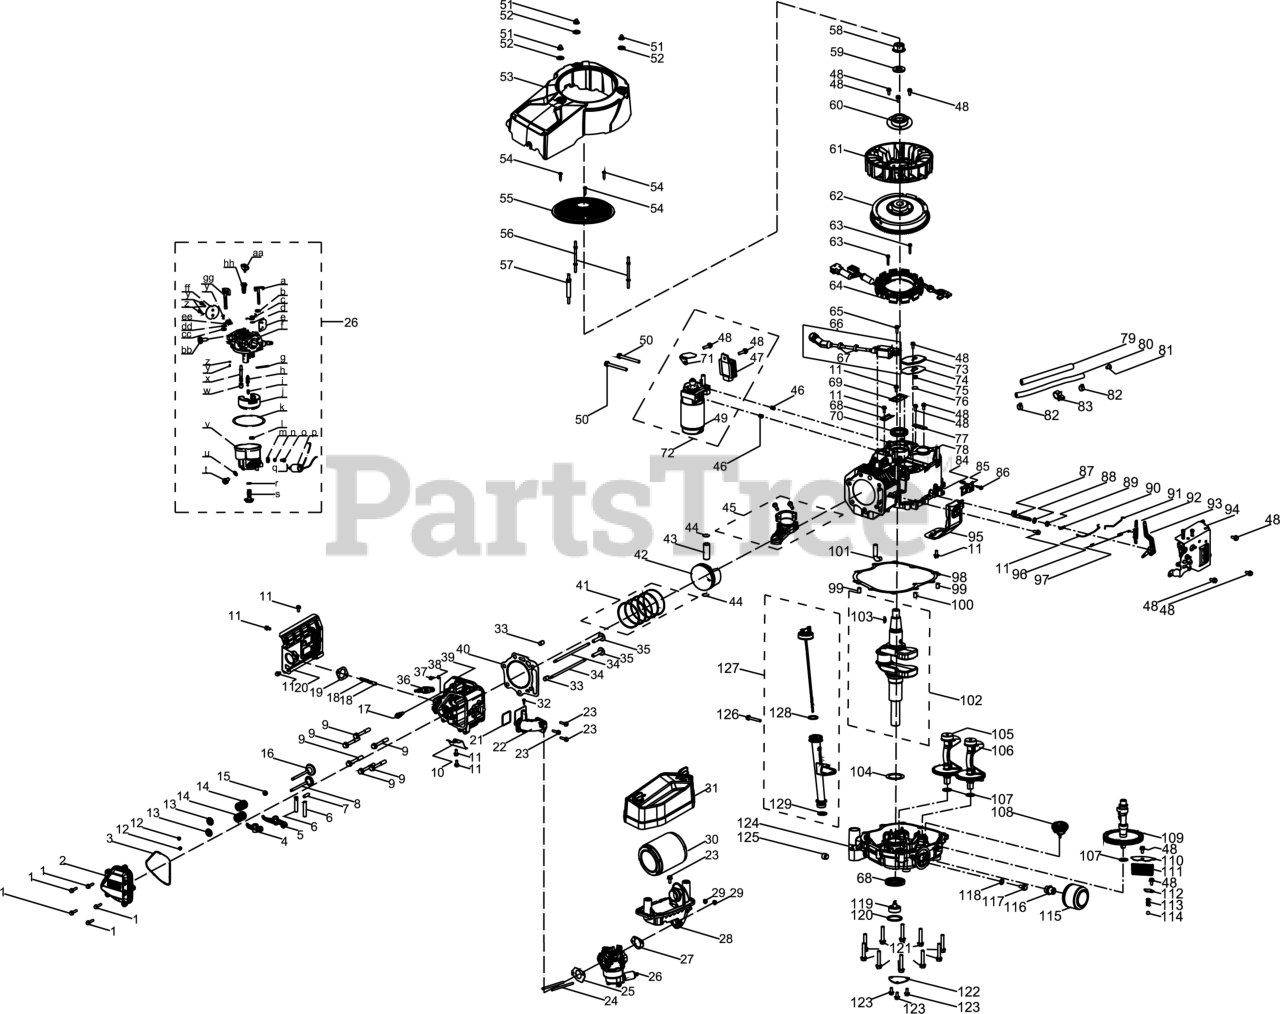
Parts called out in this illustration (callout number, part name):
1	BOLT M6-1 x 25 GR8.8
2	VALVE COVER
3	VALVE COVER GASKET
4	ROCKER ARM (INTAKE)
5	ROCKER ARM (EXHAUST)
6	ROCKER ARM SHAFT
7	CAMSHAFT PIN
8	EXHAUST VALVE
9	BOLT M10-1.25 x 70
10	HEAT SHEILD
11	BOLT M6-1 x 12 GR8.8
13	VALVE SPRING SEAT
14	VALVE SPRING
15	INTAKE VALVE SEAL
16	INTAKE VALVE
19	EXHAUST GASKET
20	BAFFLE BRACKET
21	INTAKE PIPE RING
22	INTAKE MANIFOLD
23	BOLT M6 x 22
24	STUD M6-1.00 x 92
25	INTAKE GASKET
27	AIR FLTER GASKET
28	AIR FILTER BASE
30	AIR FILTER W/PREFILTER
31	AIR FILTER COVER
32	BOLT 5.5 x 25
34	SINGLE PUSH ROD
36	SPARK PLUG (F6RTC/RN11YC/BPR6ES)
37	BOLT M5-.8 x 10
38	FLAT WASHER: 5.3 x 10 x 1
39	CYLINDER HEAD
40	CYLINDER HEAD GASKET
41	PISTON RING SET
43	PISTON PIN
44	PISTON PIN SNAP RING
45	CONNECTING ROD
45	BOLT M8-1.25 x 38 GR10.9
48	BOLT M6-1 x 14 GR8.8
49	Electric Starter
50	BOLT M8-1.25 x 80
51	ACORN NUT M6-1
53	ENGINE SHROUD
54	BOLT 5.5 x 25
55	DEBRIS SHIELD
57	STUD M6 X 113
58	NUT M20 x 1.5
59	WASHER 20.5 x 5 x 40
60	COOLING FAN PLATE
61	COOLING FAN
63	BOLT M5 x 28
64	CHARGING COIL
65	BOLT-M6-1 x 28 GR8.8
66	IGNITION MODULE
68	BREATHER SCREEN
69	WIRE PLATE
70	OIL SEAL 38 x 58 x 8
71	STARTER SHIELD BRACKET
72	Electric Starter Assy
73	BREATHER COVER
74	BREATHER COVER GASKET
75	BREATHER VALVE SPRING
76	BREATHER VALVE
79	PROTECTIVE SLEEVE TUBING
80	FUEL HOSE LOW PERMEATION 13"
82	CARBURETOR HOSE CLAMP
83	FUEL LINE SUPPORT CLAMP
84	LIMIT HOSE
85	LIMIT PLATE
86	BOLT M5 x 18
87	GOVERNOR GEAR SHAFT
88	WASHER 8 x 0.8 x 16
89	GOVERNOR SEAL
90	GOVERNOR SHAFT CLIP
91	CHOKE LINKAGE
92	GOVERNOR SPRING
93	GOVERNOR LEVER
94	THROTTLE BRACKET ASSEMBLY
95	SHROUD - RIGHT
96	THROTTLE LINKAGE
97	THROTTLE LINKAGE SPRING
98	CRANKCASE COVER GASKET
99	DOWEL PIN 9 X 14
100	DOWEL PIN 7 X 14
101	VENTING HOSE
102	CRANKSHAFT ASSEMBLY
102	DRIVE TIMING GEAR
102	BALANCE SHAFT GEAR
103	WOODRUFF KEY
104	WASHER 38.3 x 54 x 1
105	BALANCE SHAFT (LH)
106	BALANCE SHAFT (RH)
107	WASHER 17.2 x 26 x 1
108	GOVERNOR GEAR ASSEMBLY
110	FILTER COVER
111	FILTER SCREEN
112	PRESSURE RELEASE COVER
113	PRESSURE RELEASE SPRING
114	OIL PUMP STEEL BALL
115	ENGINE OIL FILTER
116	SCREW JOINT OIL FILTER ADAPTER
117	BOLT M8 x 15
118	OIL DRAIN PLUG WASHER
119	OIL PUMP ASSEMBLY
121	BOLT M8 x 45
122	OIL SEPARATOR
123	BOLT M6x12
124	CRANKCASE COVER
125	ENGINE PLUG 3/8 NPT
126	BOLT M6-1 x 45 CL5.8
127	DIPSTICK ASSEMBLY
